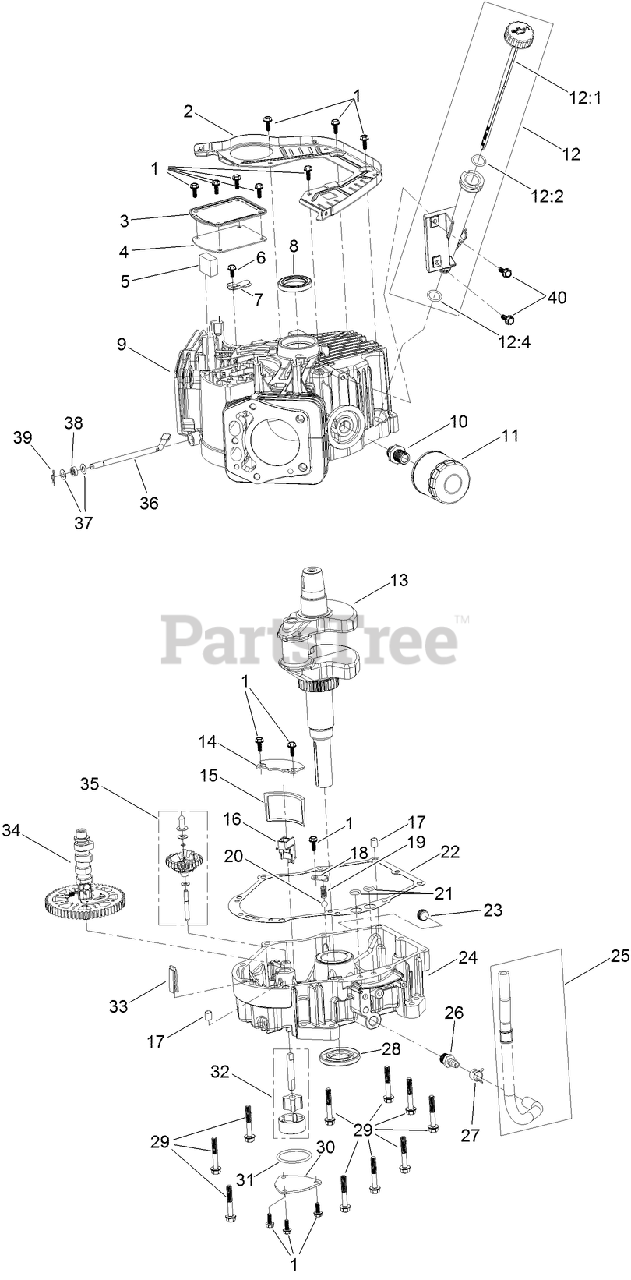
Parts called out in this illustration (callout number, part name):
1	SCREW-HHF
2	BAFFLE
3	COVER-BREATHER
4	GASKET-BREATHER
5	FILTER-BREATHER
6	SCREW-HHF
7	VALVE-BREATHER
8	SEAL-OIL
9	CRANKCASE
12	OIL TUBE ASM
12:1	DIPSTICK
12:2	O-RING
12:4	O-RING
13	CRANKSHAFT
14	COVER-SCREEN, OIL
15	SCREEN-OIL
16	RETAINER-SCREEN
17	PIN-DOWEL
18	PLATE-RETAINER
19	SPRING
20	VALVE-BALL
21	O-RING
22	GASKET-COVER, CRANKCASE
23	PLUG-DRAIN
24	COVER-CRANKCASE
25	OIL DRAIN HOSE ASM
26	FITTING-HOSE
27	CLAMP-HOSE
29	SCREW-HHF
30	COVER-OIL PUMP
31	O-RING
32	OIL PUMP ASM
33	DEFLECTOR-OIL, RUBBER
34	CAMSHAFT
36	SHAFT-GOVERNOR
37	WASHER-PLAIN
38	SEAL-OIL
39	PIN-HAIR
40	SCREW-HHF
